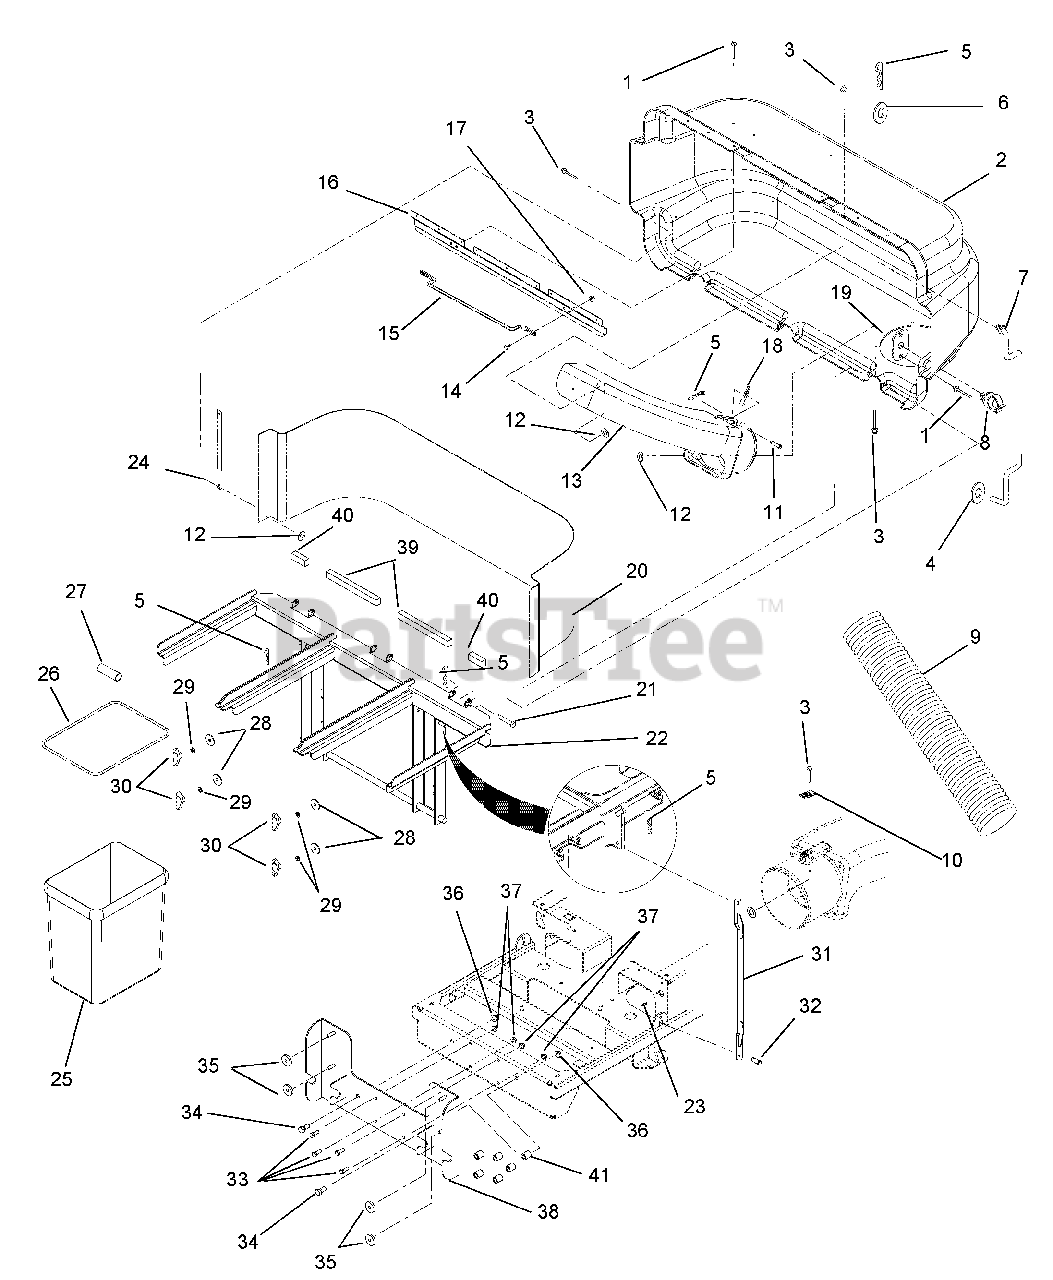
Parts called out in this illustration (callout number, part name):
1	Rivet, Pop .187 x .402
2	Cover, Bagger with Decal
3	Rivet, Pop .187 x .375
4	Retainer, .38 Push-On
5	Pin, Hair
6	Washer-Flat-Steel .046 x .812 x .065
7	Prop Rod, Bagger
8	Clip .38
9	Bagger Hose 45"
10	Thumb Latch
11	Pin, Clevis .31 x 2.62 Grade 5
12	Washer, Flat-Steel .219 x .50 x .049
13	Boot, Upper
14	Bolt, Round Head Square Neck .25-20 x .75 Grade 5
15	Bagger Handle
16	Latch, Cover
17	Nut, Locking-Top-Flange .25-20
18	Indicator, Flow
19	Plate, Rod Clip
20	Screen, Bagger
21	Pin, Clevis .368/.373 x 3.25
22	Weldment, XL Bagger Frame
23	Pin, Hair, External- #16
24	Strap, Cover
25	Bag, Mesh
26	Frame, Bag
27	Hose, .38 x .50 x 3.00 Vinyl
28	Washer, Flat Steel .390 x 1.5 x .125
29	Washer, Lock .38 x .094
30	Knob, Wing .38-16
31	Strap, Bagger
32	Pin, Clevis .38 x .75
33	Bolt, Hex .38-16 x 2.50 Grade 5
34	Bolt, Hex .50-13 x 2.50 Grade 5
35	Washer, Flat Steel .406 x 1.50 .245
36	Nut, .50-13 Nyloc Flange
37	Nut, .38-16 Nyloc Flange
38	Mount, Rear Bagger
39	Grass Block, 10.5-In. Foam
40	Grass Block, 4-In. Foam
